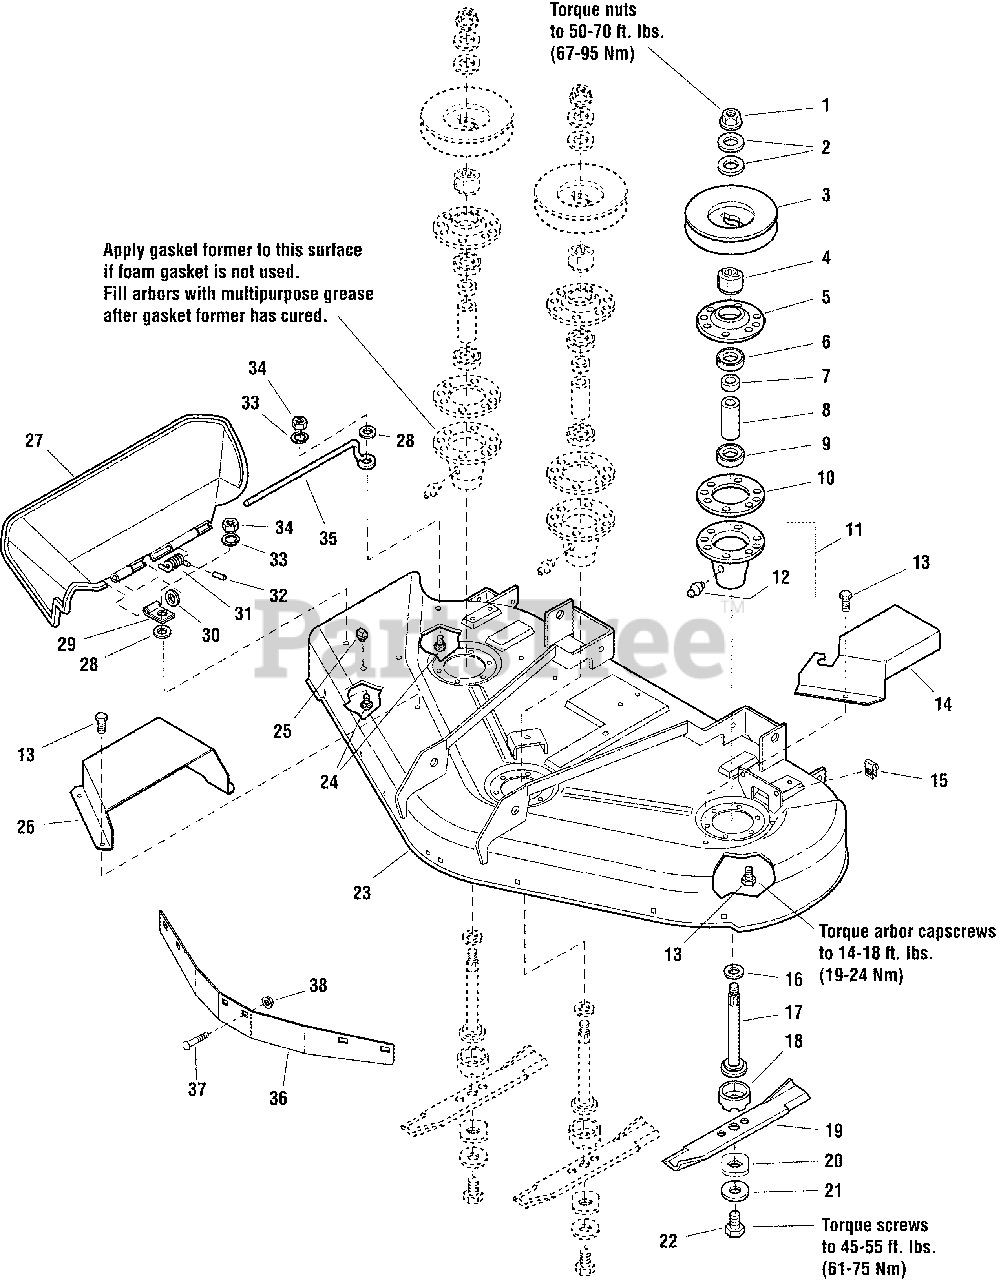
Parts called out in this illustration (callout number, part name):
1	NUT, HEX FLANGE, 9/16-18
2	WASHER, BELLEVILLE, 9/16
3	PULLEY
4	HUB
5	COVER, ARBOR HOUSING
6	BEARING, BALL, 3/4 X 1-3/4 X 5/8
7	SPACER, 21/32 X 3/4 X 5/8
8	SPACER, 11/16 X 5/32 X 2-11/16
9	BEARING, BALL, 11/16 X 1-9/16 X 15/32
10	SEAL, FOAM
11	ARBOR HOUSING ASSEMBLY
12	FITTING, GREASE
13	BOLT TAPTITE, 5/16-18 X 3/4
14	COVER, ARBOR, LH
15	BODY CLIP, 5/16-18
16	WASHER, 9/16, BLACK
17	SHAFT, ARBOR
18	SHIELD, GRASS, LOWER
19	BLADE, MOWER, 18-1/8
20	WASHER, HEX, 11/16 X 2
21	WASHER, SPRING, 15/32, BLACK
22	BOLT, 7/16-14 X 1-1/4
23	WELD, MOWER DECK, 50", 400Z MODELS
24	CARRIAGE BOLT, 1/4-20 X 7/8
25	PLUG, HOLE
26	COVER, ARBOR, RH
27	DEFLECTOR, PLASTIC
28	WASHER, 1/4, BLACK
29	CLAMP
30	WASHER, 5/16, BLACK
31	SPRING
32	VINYL CAP
33	WASHER, LOCK, 1/4
34	NUT, HEX, 1/4-20
35	ROD, DEFLECTOR
36	BAFFLE - FRONT 44/50 - BLACK
37	BOLT, 5/16-18 X 3/4 CARRIAGE
38	NUT, 5/16-18 HEX NYLOCK FLANGE
